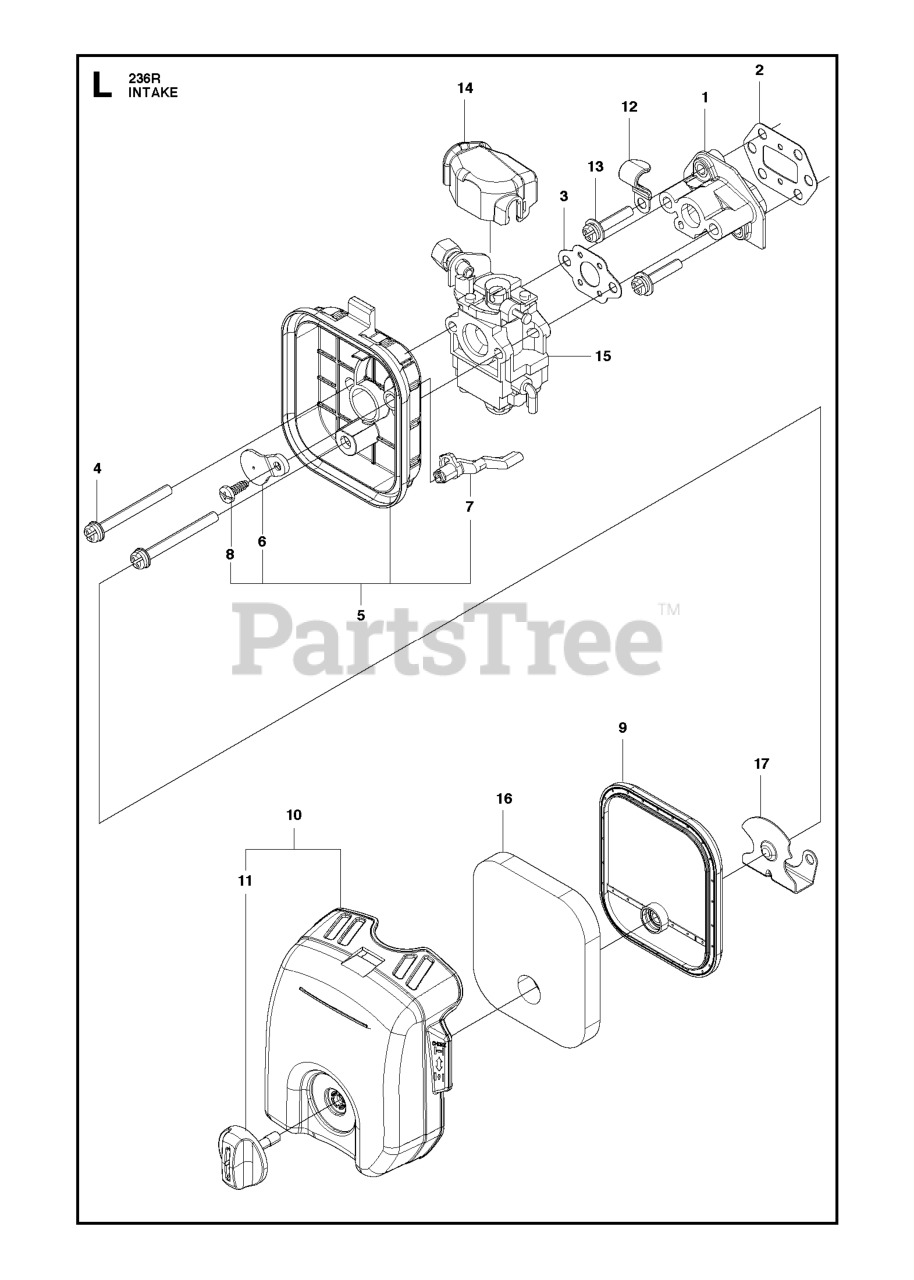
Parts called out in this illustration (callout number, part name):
6	PLATE, CHOKE
7	LEVER.CHOKE
8	SCREW
12	CLAMP
